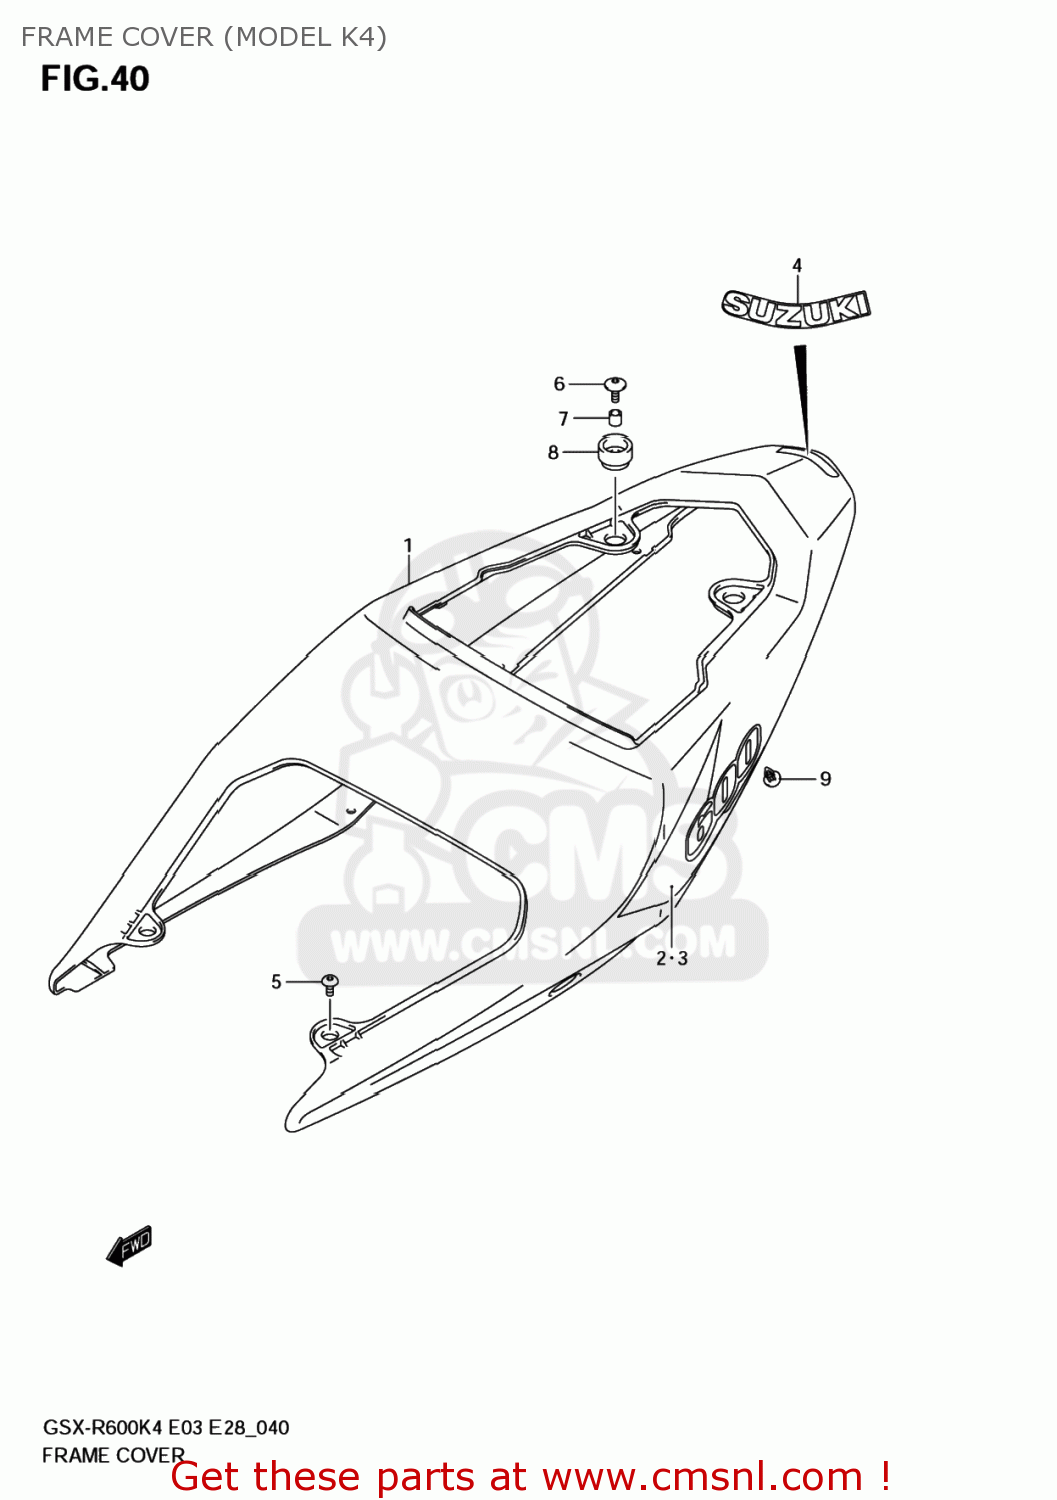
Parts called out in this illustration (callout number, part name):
1	COVER ASSY,FRAME(WHITE)
2	TAPE,FRAME COVER,R
3	TAPE,FRAME COVER,L
4	EMBLEM,SUZUKI
5	SCREW(6X16)
6	SCREW(6X16)
7	SPACER(6.5X10X9.4)
8	CUSHION
9	CLIP(BLACK)
